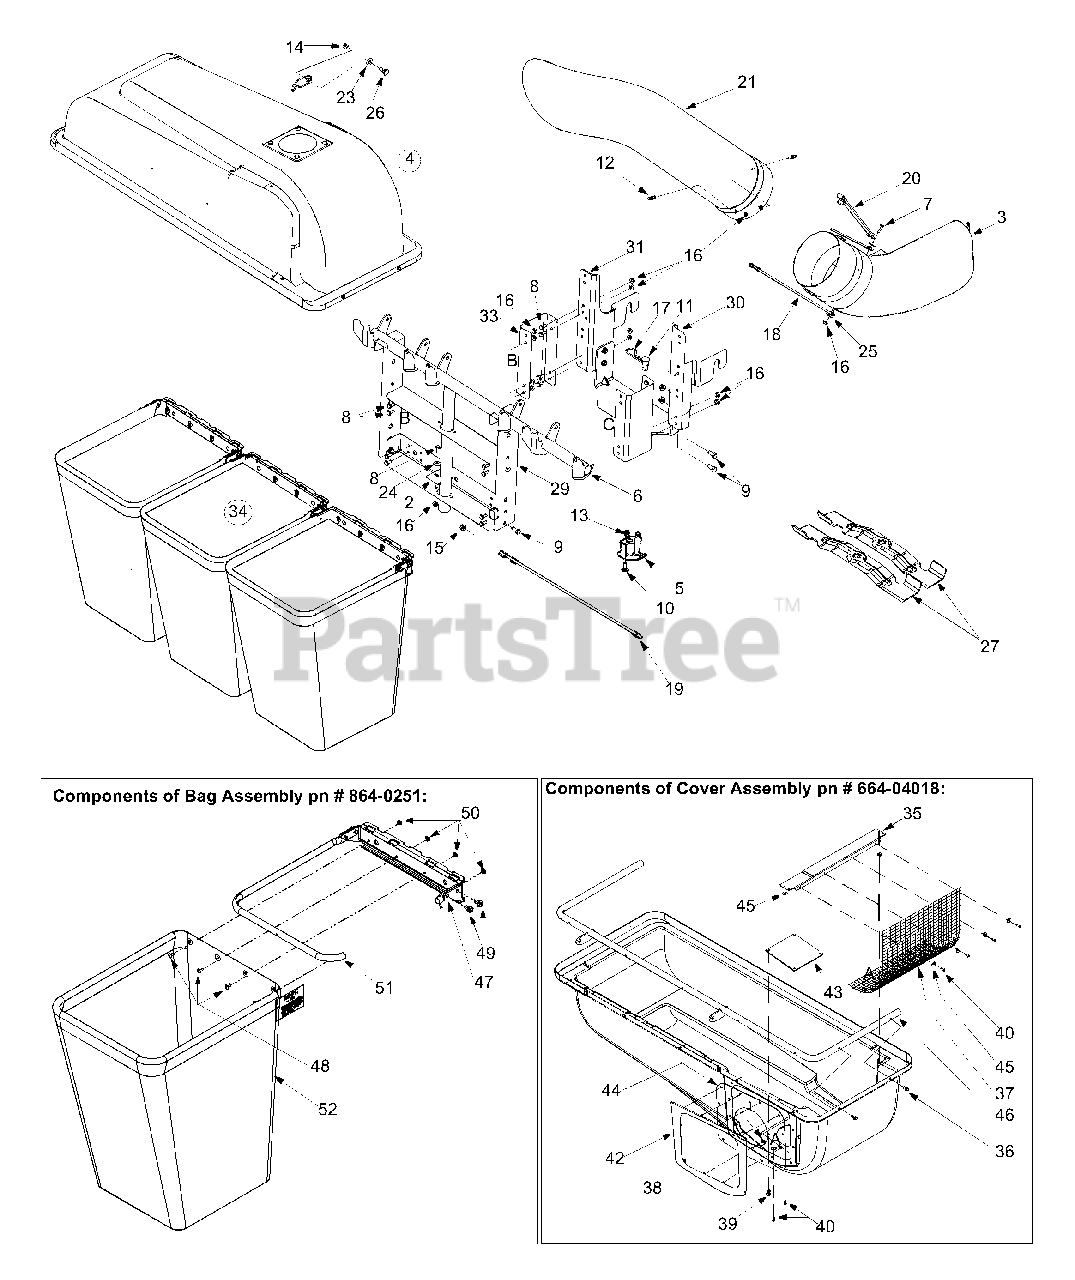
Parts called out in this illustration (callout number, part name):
3	Chute Elbow
4	Cover Assembly
8	Hex Bolt 1/4-20 x 0.620
9	Hex Bolt 5/16-18 x 0.75
10	Carriage Bolt
11	Clevis Pin
12	Grasscatcher Pin
13	Hex Lock Nut 3/8-16
14	Flange Lock Nut 3/8-16
15	Flange Lock Nut 5/16-18
16	Flange Lock Nut 1/4-20
17	Hairpin Clip
18	Chute Strap
20	Chute Strap
21	Catcher Tube
23	Beleville Washer
24	Bell Washer
25	Flat Washer
26	Shoulder Screw
27	Blade
37	Screen
38	Push Nut
39	Ratchet Clip
40	Pop Rivet
41	Grass Bag Cover
42	Retainer Seal
43	Plastic Plate
44	Grass Bag Seal
45	Flat Washer
48	Machine Screw
49	TT Screw 5/16-18 x 0.625
50	Hex Sems Nut
